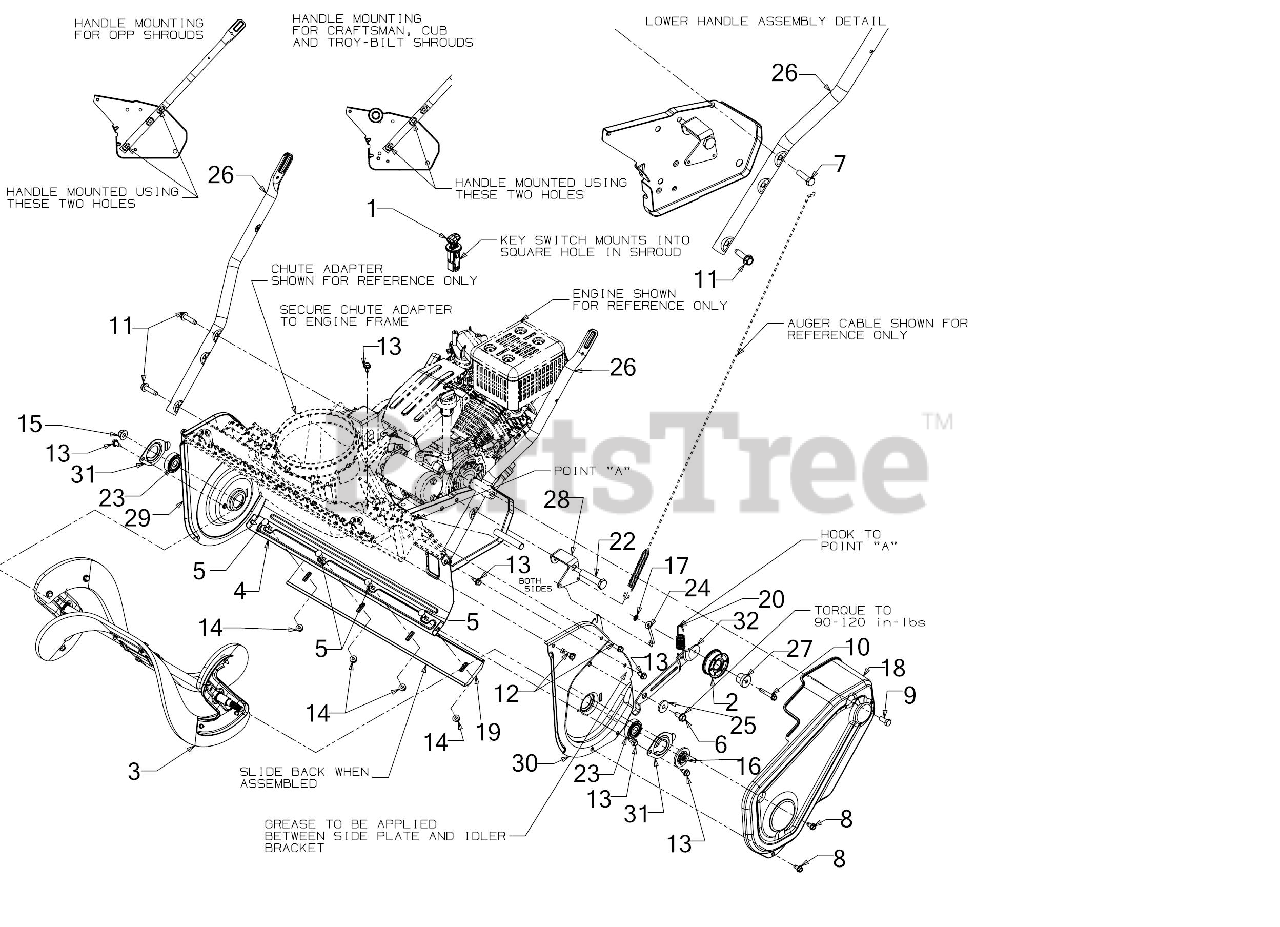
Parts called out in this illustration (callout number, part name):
1	IGNITION SWITCH
2	IDLER PULLEY ASSEMBLY
3	21" AUGER ASSEMBLY
4	FRAME ASSEMBLY
5	CARRIAGE BOLT 1/4-20 x .62
6	SCREW 5/16-18 x .750
7	SCREW 5/16-24 x 1.25 GR5
8	SCREW 1/4-20 X.500
9	SCREW 5/16-24 x .750 GR5
10	SCREW 1/4-20 x 1.50"
11	SCREW 5/16-18 x 1.25
12	SCREW 1/4-15 x .750
13	SCREW 1/4-20X.625
14	FLANGE LOCK NUT
16	PULLEY HUB 1/2"
17	RETAINER-BOLT .25ID x .50OD
19	SHAVE PLATE
20	EXTENSION SPRING
22	SHOULDER BOLT
23	BALL BEARING
24	WIRE DRIVE CABLE SUPPORT
25	SHOULDER SPACER
27	SHOULDER SPACER
28	CLUTCH CABLE BRACKET
29	AUGER HOUSING PLATE (RH)
30	AUGER HOUSING PLATE (LH)
31	AUGER HOUSING BEARING CUP
32	IDLER BRACKET
